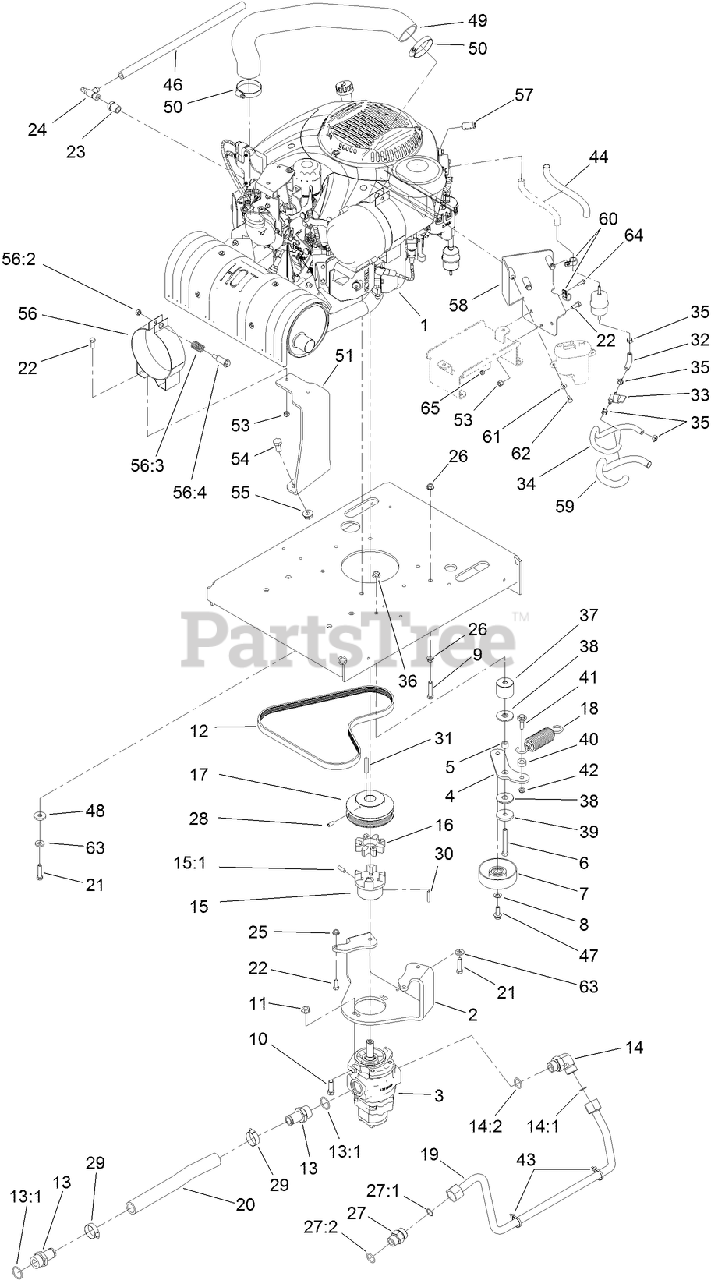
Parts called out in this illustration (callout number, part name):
1	ENGINE-KOHLER
2	PLATE-MOUNT, PUMP
3	GEAR PUMP ASM
4	ARM-IDLER
5	BUSHING-LEVER, LIFT
6	SCREW-HH
7	PULLEY-IDLER
8	WASHER-FLAT
9	SCREW-HH
10	SCREW-HH
11	NUT-HF
12	BELT-V
13	FITTING-STR
13:1	O-RING
14	FITTING-ELBOW-90
14:1	O-RING
14:2	O-RING
15	HUB-COUPLER
15:1	SCREW-SET
16	SPIDER
17	PULLEY-ENGINE
18	SPRING-EXTENSION
19	TUBE-HYD
20	HOSE-SUCTION
21	SCREW-HH
22	SCREW-HH
23	BUSHING
24	Valve-Drain, Oil
25	NUT-HF
26	NUT-HHF, WHIZ
27	FITTING-STR
27:1	O-RING
27:2	O-RING
28	SCREW-SET, HSH
29	CLAMP-HOSE
30	KEY-SQUARE
31	KEY-SQUARE
32	HOSE-FUEL
33	VALVE-FUEL
34	Fuel Line
35	CLAMP-HOSE
36	NUT-HF, NI
37	SPACER-IDLER
38	WASHER-FRICTION, COMPOSITE
39	WASHER-PLAIN
40	SPACER
41	SCREW-SHOULDER, HWH
42	NUT-LOCK, NI
43	TIE-CABLE
44	SLEEVE-THERMAL
47	SCREW-HHF
48	WASHER
49	HOSE-INTAKE, AIR
50	CLAMP-HOSE
51	PLATE-MOUNT, FILTER
53	NUT-LOCK, NI
54	SCREW-HH
55	NUT-HHF
56	BAND-MOUNTING, AIR CLEANER
56:3	SPRING
56:4	NUT
57	FERRITE-SNAP ON
58	BRACKET-PUMP, FUEL
59	SLEEVE-THERMAL
60	CLAMP-CABLE
61	WASHER-FLAT
62	SCREW-HH
63	WASHER-BELLEVILLE
64	SCREW-HH
65	NUT-LOCK, NI
